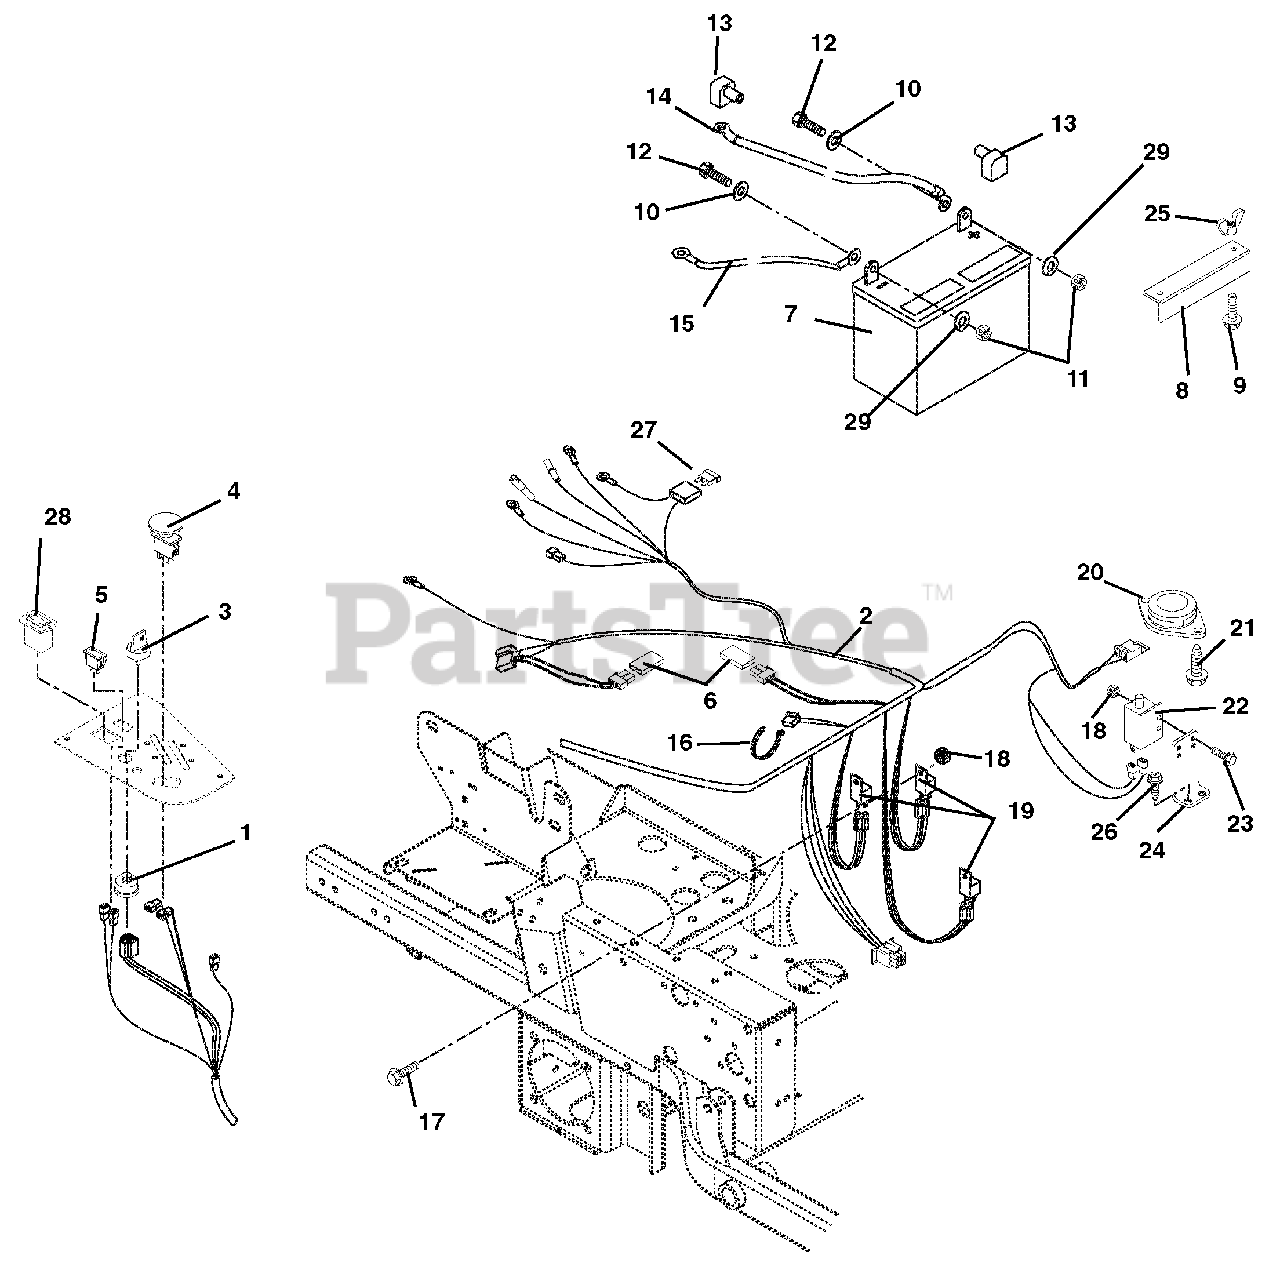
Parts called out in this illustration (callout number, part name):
1	Key Switch
2	Harness, IZ/CZ
3	Key with Shield
4	Switch, Clutch With Retainer Ring
5	Light, Indicator
6	Diode, Connector Shell
8	Hold Down
9	Bolt, Round Head Square Neck .25-20 x 7.50
10	Washer, Flat Steel .281 x .620 x .065
11	Nut, Locking Top Flange .25-20
12	Bolt, Hex .25-20 x .75 Grade 5
13	Insulator
14	Cable, Positive Battery 26 Inch
15	Cable, Negative Battery 24 Inch
16	Cable Tie
17	Screw, Machine 10-24 x .50 Hex Washer Head
18	Nut, Locking Nylon 10-24 With Insert
19	Relay, Sealed with Diode (Included with Harness)
20	Seat Switch
21	Screw, Tapping 12-24 x .50 Hex Washer Head
22	Switch, Double Pole N.O/N.O.
23	Screw, Machine 10-24 x .75 Hex Washer Head
24	Mount, Brake Switch
25	Nut, Locking Wing .25-20
26	Screw, Tapping .25-20 x .50 Hex Washer Head
27	Fuse, 30 Amp (Included with Harness)
28	Hour Meter
29	Washer, Locking .25 x .062 Regular
